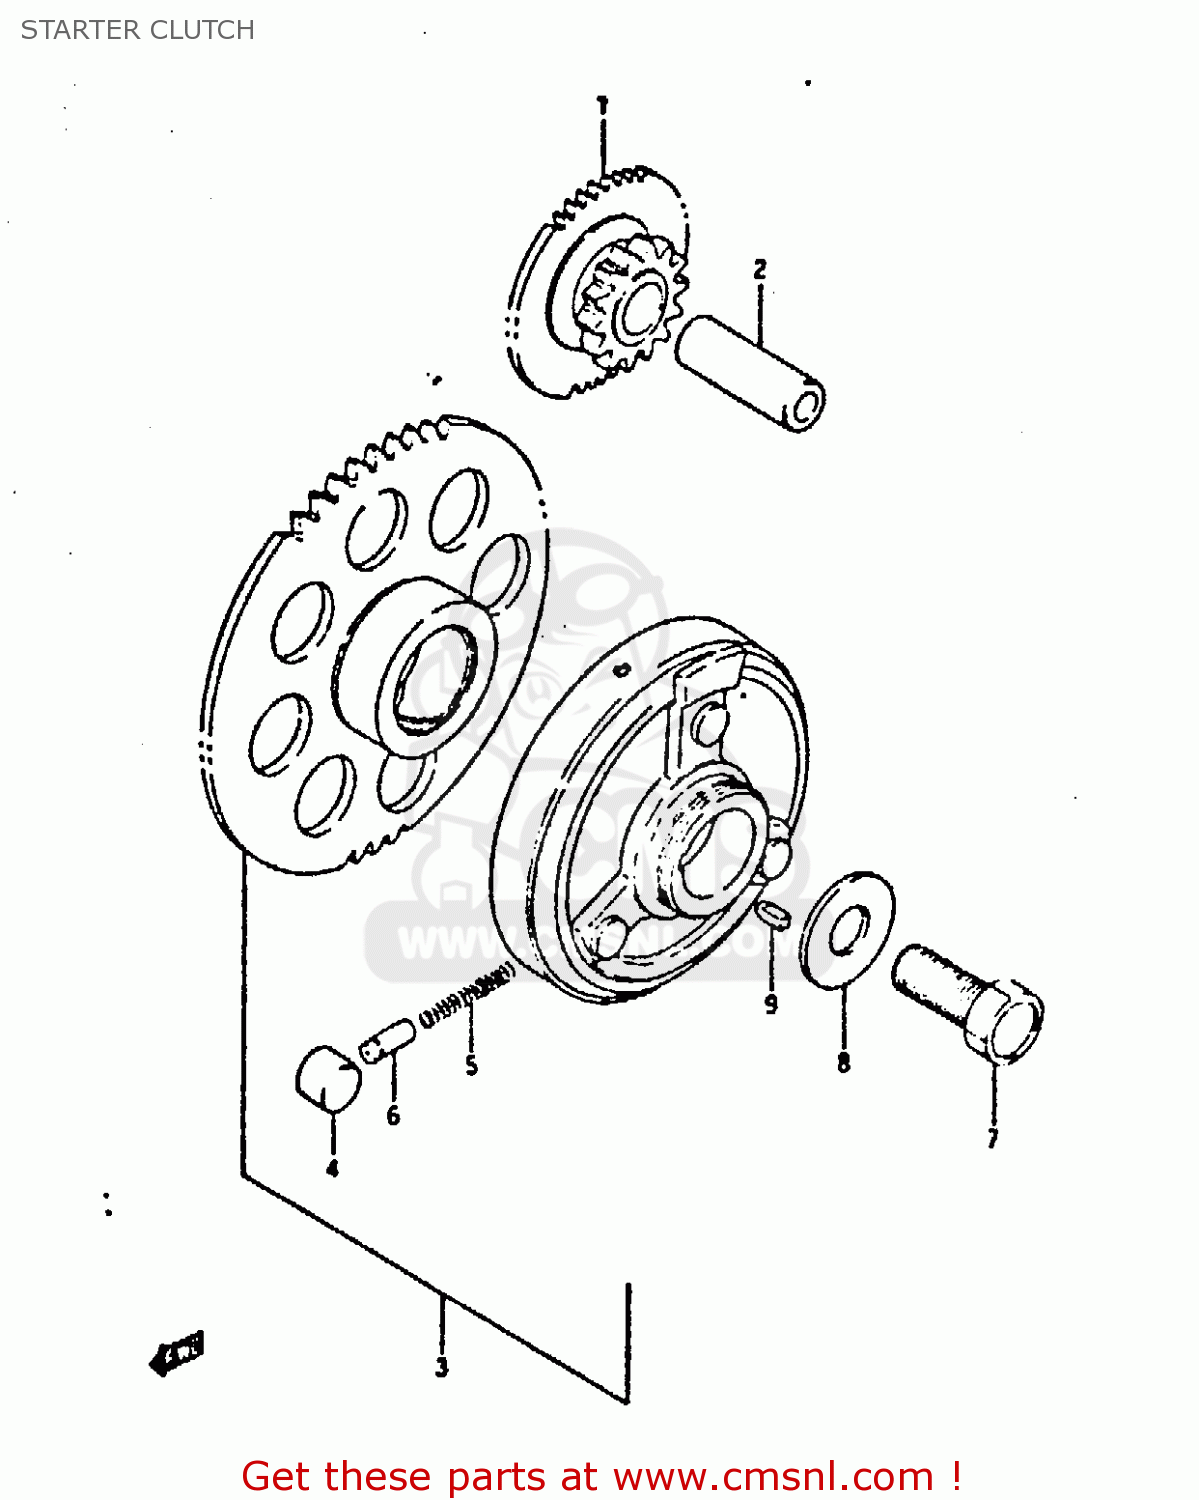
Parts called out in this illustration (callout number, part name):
1	STARTER IDLE GE
2	PIN(7.4X13X40)
3	STARTKOPPELING
4	ROLLER(15X13)
5	SPRING
6	PIECE,PUSH
7	BOLT
8	WASHER(12X30X3)
9	KEY
